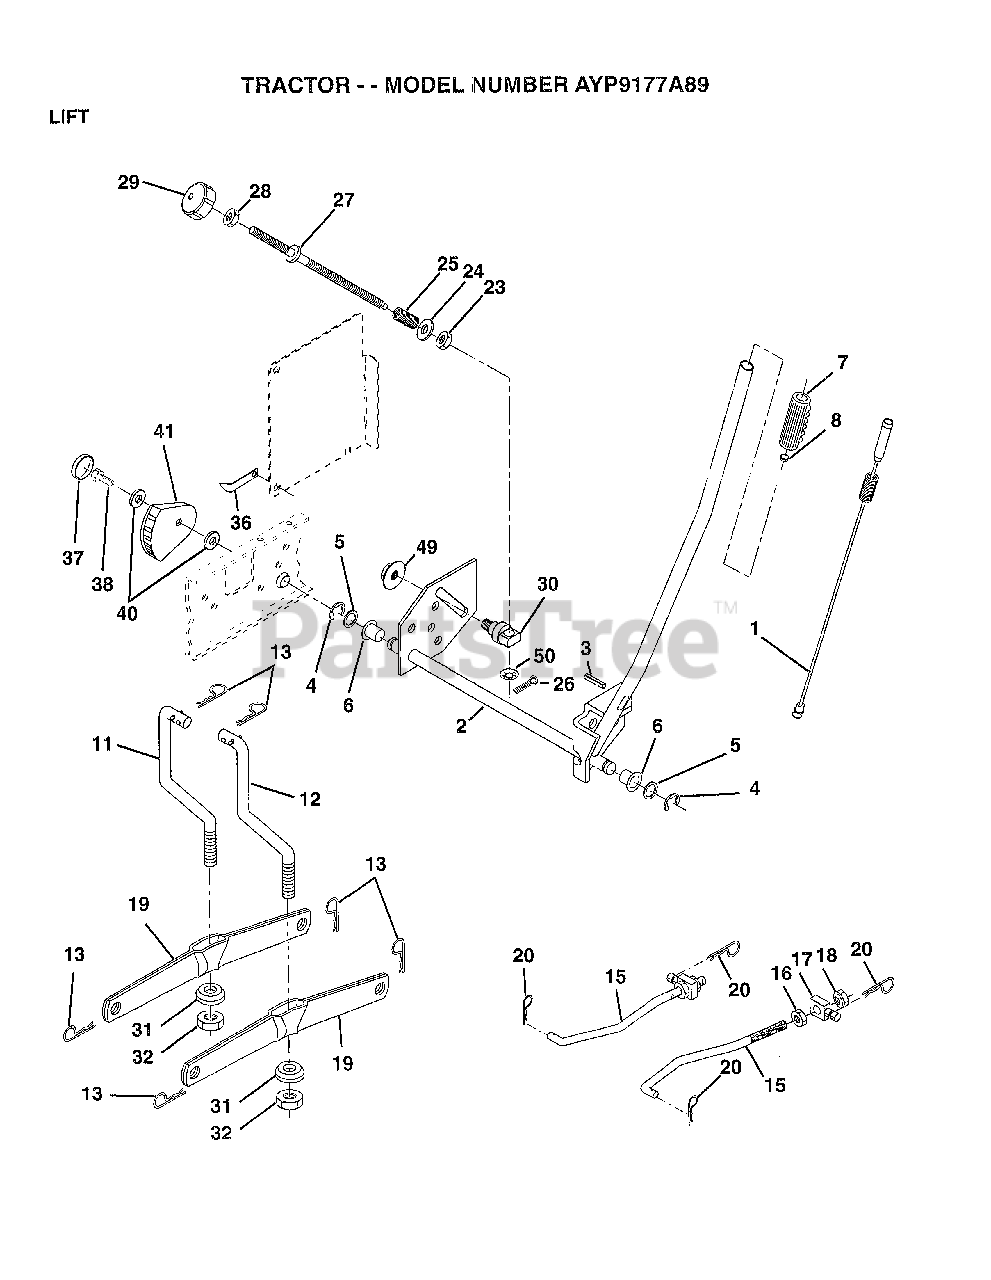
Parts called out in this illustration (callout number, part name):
1	WIRE ASM W.SPRING
2	SHAFT ASM LIFT RH
3	PIN-GROOVE LT
5	WASHER
6	NYLON BEARING
7	GRIP HANDLE
15	LINK.FRONT
16	NUT
17	TRUNION
18	NUT.LK.W/WSH.1/2.
19	ARM SUSP REAR
20	RETAINER.SPRING
23	NUT T
24	WASHER
25	SPRING T
28	NUT
29	KNOB INF 3/8-16
30	TRUNNION
31	BEARING PVT LH
32	NUT.CROWNLOCK.3/8
36	POINTER-INDICAT
37	"PLUG,HOLE"
38	SCREW
40	WASHER
41	INDICATOR HEIGHT
49	NUT.HXFLG.LOCK.
50	NUT PUSH M
